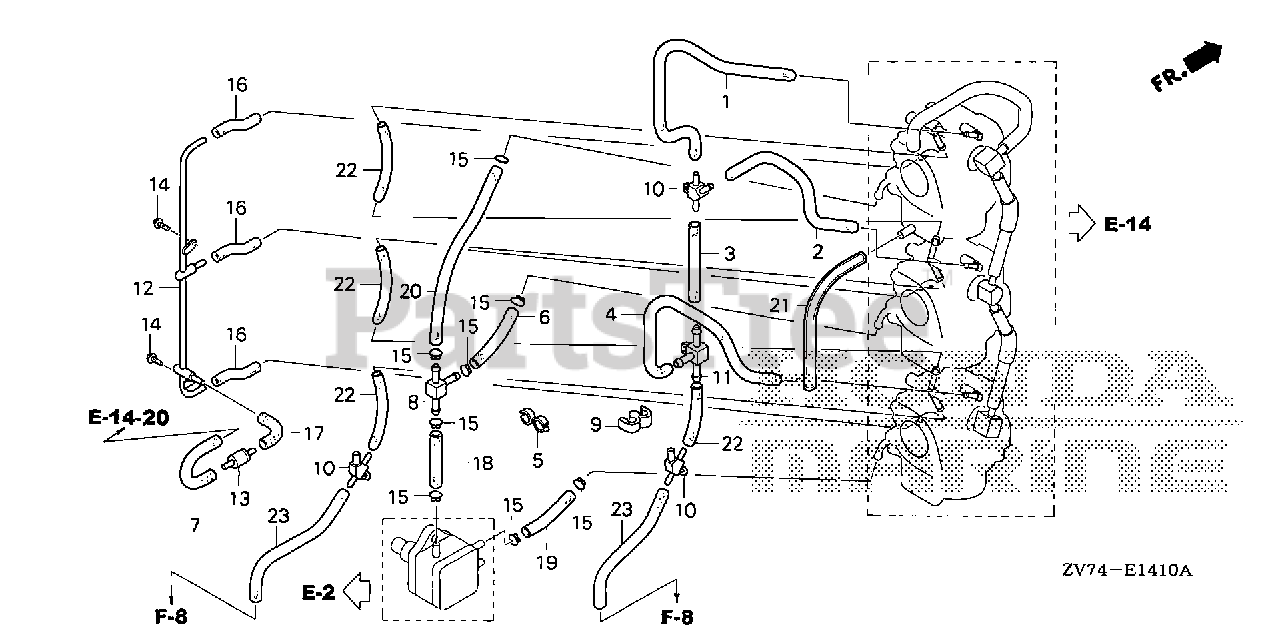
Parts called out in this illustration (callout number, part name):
1	TUBE A, AIR VENT
1	TUBE, AIR VENT (A)
2	TUBE B, AIR VENT
3	TUBE C, AIR VENT
4	TUBE D, AIR VENT
5	CLAMP, FUEL TUBE (A)
6	TUBE C, FUEL
7	TUBE D, FUEL
8	PIPE, THREE WAY JOINT
9	CLAMP, TUBE (7.5X2)
10	JOINT, THREE WAY
11	JOINT, THREE WAY
12	PIPE, INSTALL
13	VALVE, DASHPOT CHECK
14	BOLT, FLANGE (5X10) (CT200)
15	CLIP, TUBE (B10)
16	BULK HOSE, FUEL (3.5X3000) (3.5X45)
17	BULK HOSE, FUEL (3.5X3000) (3.5X65)
18	BULK HOSE, FUEL (5.5X3000) (5.3X55)
18	TUBE, FUEL
19	BULK HOSE, FUEL (5.5X3000) (5.3X70)
19	TUBE, FUEL (5.3X55)
20	BULK HOSE, FUEL (5.5X3000) (5.3X175)
20	TUBE, FUEL (5.3X70)
21	BULK HOSE, VINYL (4.5X8X1000) (95003-09001-60M)
22	BULK HOSE, VACUUM (4.5X1000) (4.5X93)
23	BULK HOSE, VACUUM (4.5X1000) (4.5X110)
